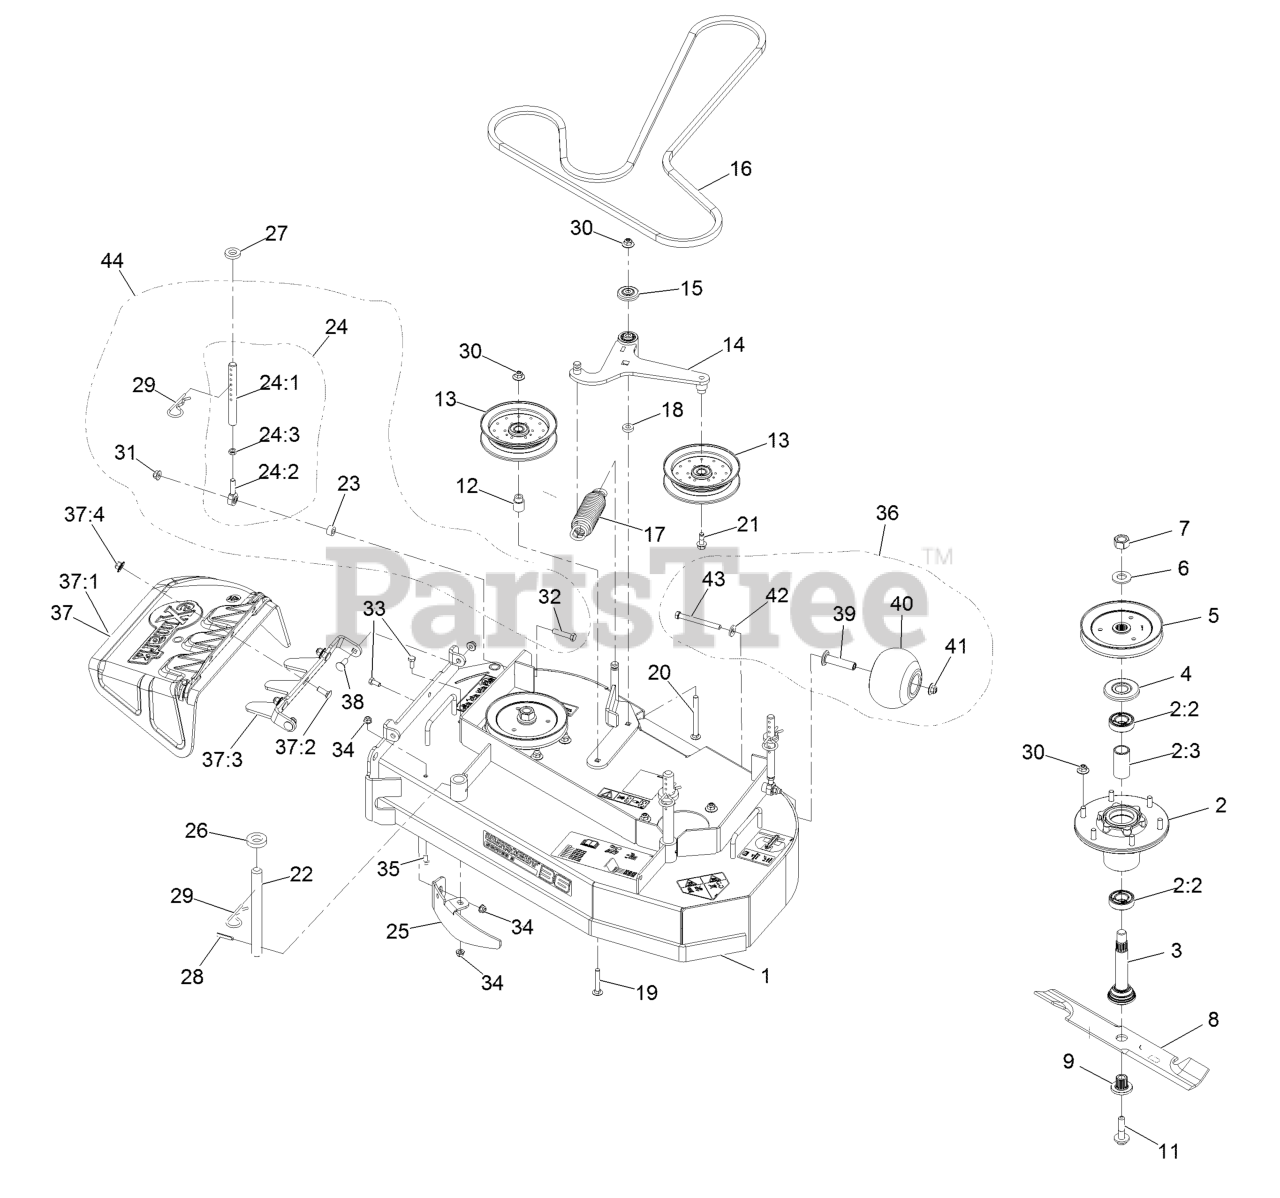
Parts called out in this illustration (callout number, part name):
1	ASM, Deck W/ Decals, 36"
2	ASM-Cutter Hsg With Bearings
2:2	Bearing-Ball
2:3	Spacer-Bearing
3	ASM-Spindle And Seal
4	Guard,Bearing Top .989
5	Sheave,Blade Drive 6.50
6	Washer-Spring Disc 3/4
7	Nut-Hex
8	Blade-Extreme 2, 18.00"
8	Blade-Notched
8	Blade, Mulching
8	Blade, Low Lift
8	Blade, Solid
9	Bushing, Splined
11	Screw-Sems 1/2-20 X 2.19
12	Bushing-Idler
13	Idler-Pulley, Flanged
14	ASM-Arm, Idler
15	Guard-Top
16	Belt-5V
17	Spring-Extension
18	Spacer
19	Bolt-Carriage 3/8-16 X 2 1/4
20	Bolt-Carriage 3/8-16 X 4
21	Screw-Hfh
22	Rod, Deck Support
24	Link Assy
24:1	Link, Rear Deck Support
24:2	Balljoint
24:3	Nut-Jam 3/8-24
25	Baffle, Dogleg
26	Spacer-Deck Support
27	Spacer-Blade Drive
28	Rollpin 1/4 X 1 1/2
29	Hairpin-Cotter #206
30	Nut-Nyloc 3/8-16 Flg
31	Nut-Nyloc 3/8-16 Flg
32	Screw-HH 3/8-16 X 1 3/4
33	Screw-HH 5/16-18 X 3/4
34	Nut-Nyloc 5/16-18 Flg
35	Screw-HH 5/16-18 X 5/8
36	Kit, Anti-Scalp Roller
37	ASM, Discharge Chute
37:1	Chute, Discharge
37:2	Bracket, Discharge Chute
37:3	Bolt-Carriage 3/8-16 X 1
37:4	Nut-Nyloc 3/8-16 Flg
38	Bolt-Carriage 3/8-16 X 1
39	Axle, Roller
40	Roller-Anti-Scalp
41	Nut-Nyloc 3/8-16 Flg
42	Washer-Spring Disc 3/8
43	Screw-HH 3/8-16 X 3 3/4 GR 8
44	Kit, Support Link W/Pin
